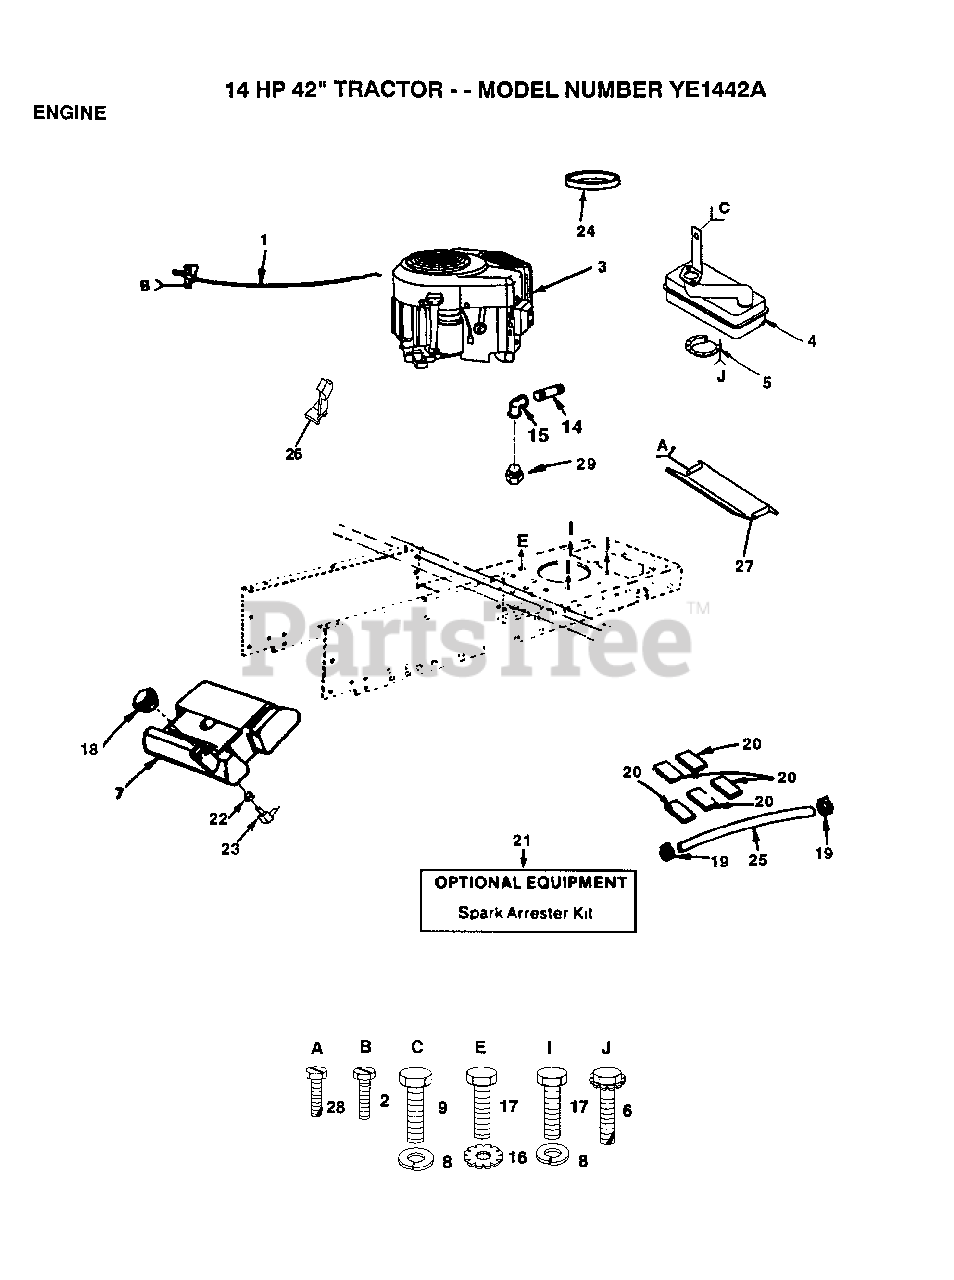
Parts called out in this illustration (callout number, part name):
2	SCREW LT
4	MUFFLER
5	DEFLECTOR.222573
8	LOCKWASHER
9	BOLT
14	PIPE NIPPLE LT
15	ELBOW
16	LOCKWASHER.5/16.E
19	HOSE CLAMP
20	PAD-SPACER LT
22	BUSHING OUTLET T
23	FUEL TANK STEM GT
24	"STRIP,FOAM"
25	FUEL LINE T
26	"STOP,THROTTLE"
27	HEAT SHIELD
28	SCREW
